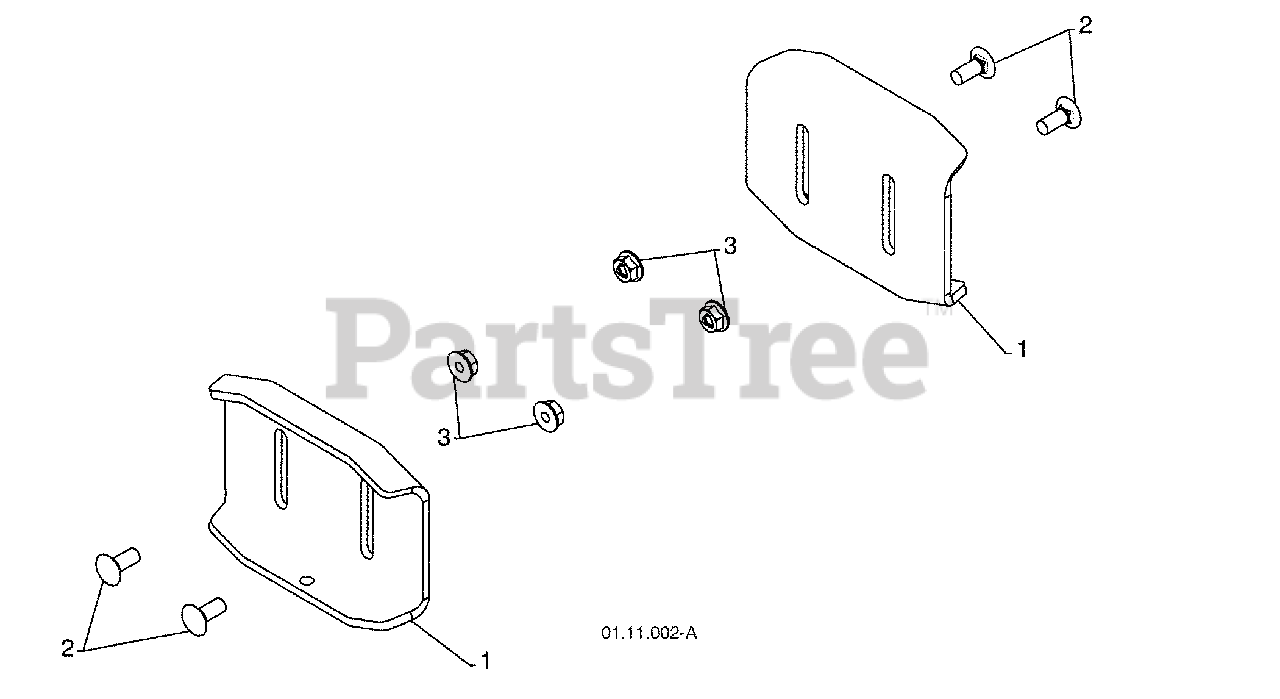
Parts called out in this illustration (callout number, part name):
1	SKID PLATE
2	CARRIAGE BOLT 5/16-18 X .750
3	NUT 5/16-18
